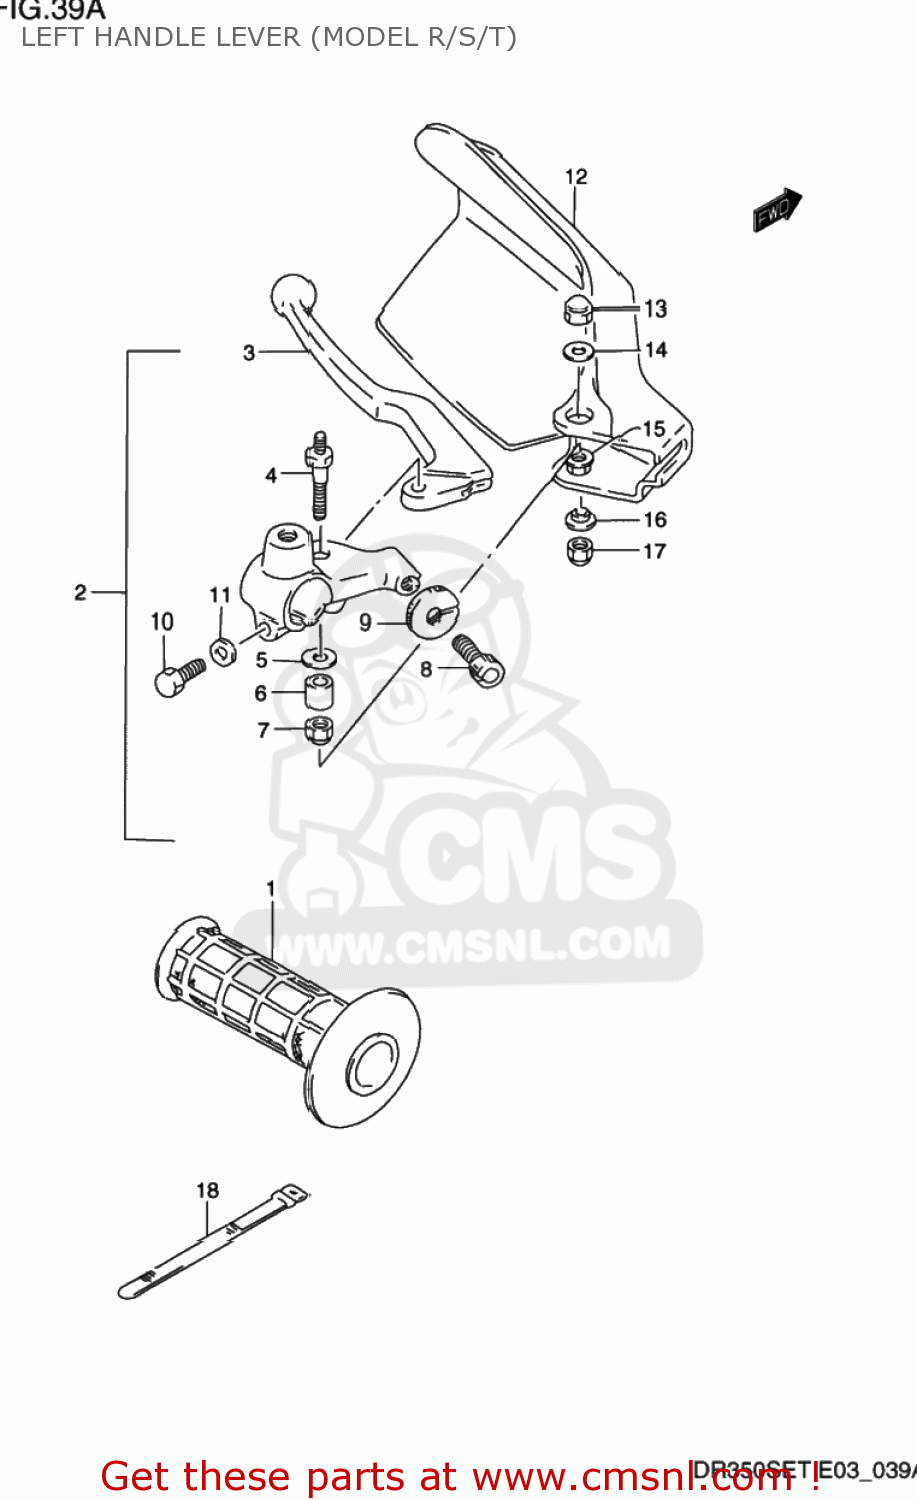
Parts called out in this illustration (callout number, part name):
1	GRIP,L
2	LEVER ASSY,CLUTCH
3	LEVER,CLUTCH
4	BOLT,LEVER SET
5	WASHER
6	SPACER,LEVER SET
7	NUT
8	ADJUSTER,CABLE
9	NUT,LOCK
10	BOLT
11	WASHER
12	COVER,KNUCKLE,LEFT
13	NUT
14	WASHER(6.5X20X1.6)
15	WASHER(6.5X16X1.2)
16	WASHER
17	NUT 6MM
18	CLAMP(L:120)
